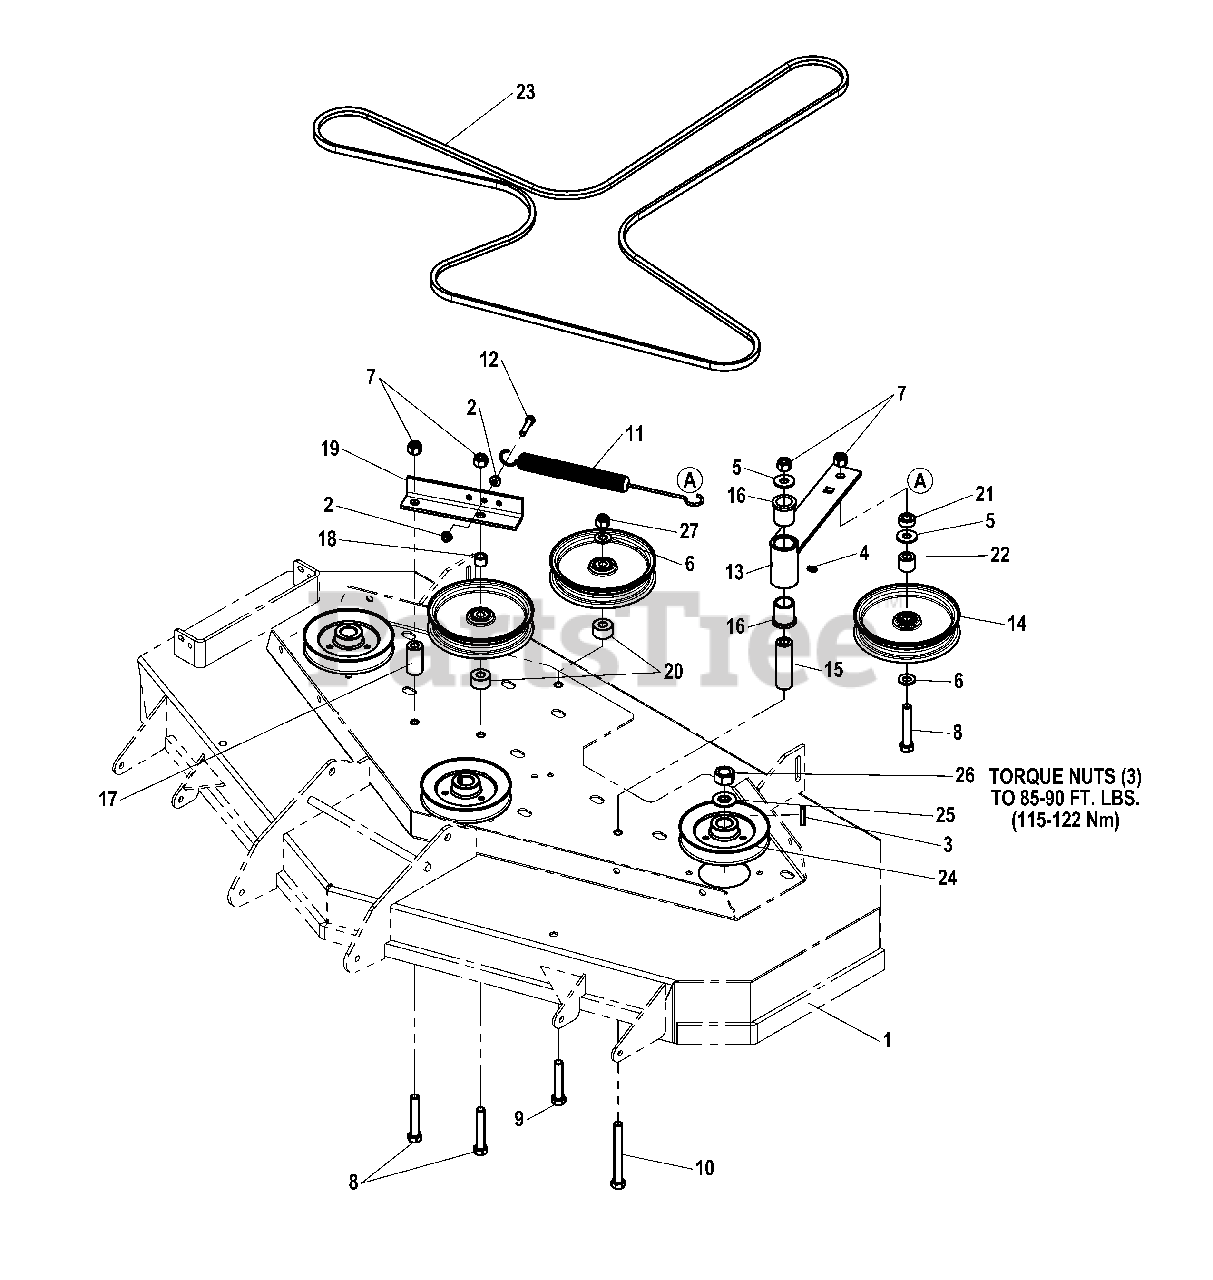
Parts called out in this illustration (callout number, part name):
1	MOWER DECK
2	NUT, 5/16-18 Hex Small Serrated Flange
3	KEY, 1/4 SQ. X 1-1/4
4	GREASE FITTING
5	WASHER, 1/2" USS
6	WASHER, 1/2" SAE
7	NUT, 1/2-13 Hex Nylon Lock
8	BOLT, 1/2-13 x 3-1/4
9	BOLT, 1/2-20 x 2-1/2
10	BOLT, 1/2-13 X 4-3/4
11	SPRING, Extension, Swivel End
12	BOLT, 5/16-18 x 1-1/2
13	ASSM, IDLER ARM - BLK - 5407039A (SV)
14	*PULLEY, FLAT IDLER, 6-3/4"
15	SPACER, .52 X 1.00 X 3.42
16	BUSHING, Flange
17	SPACER, .50 X 1.00 X 2.00
18	SPACER, .51 X .75 X .56
19	ANCHOR, SPRING
20	SPACER, .52 X 1.25 X .70
21	SPACER, .52 X 1.00 X .44
22	SPACER, .52 X 1.00 X .88
23	BELT, 48" DECK
23	BELT, 5V, 160.60"EL, LRG ARAMID, WRP, RC
24	PULLEY, 5.540OB X 3985ID, SINGLE B-SEC (48" Deck)
24	PULLEY, Spindle, 6.12" (52" Deck)
25	WASHER, 3/4" Belleville (Included with Complete Spindle Assembly)
26	NUT, 3/4-16 Hex (Included with Complete Spindle Assembly)
27	NUT, 1/2-20 Hex Nylon Lock
